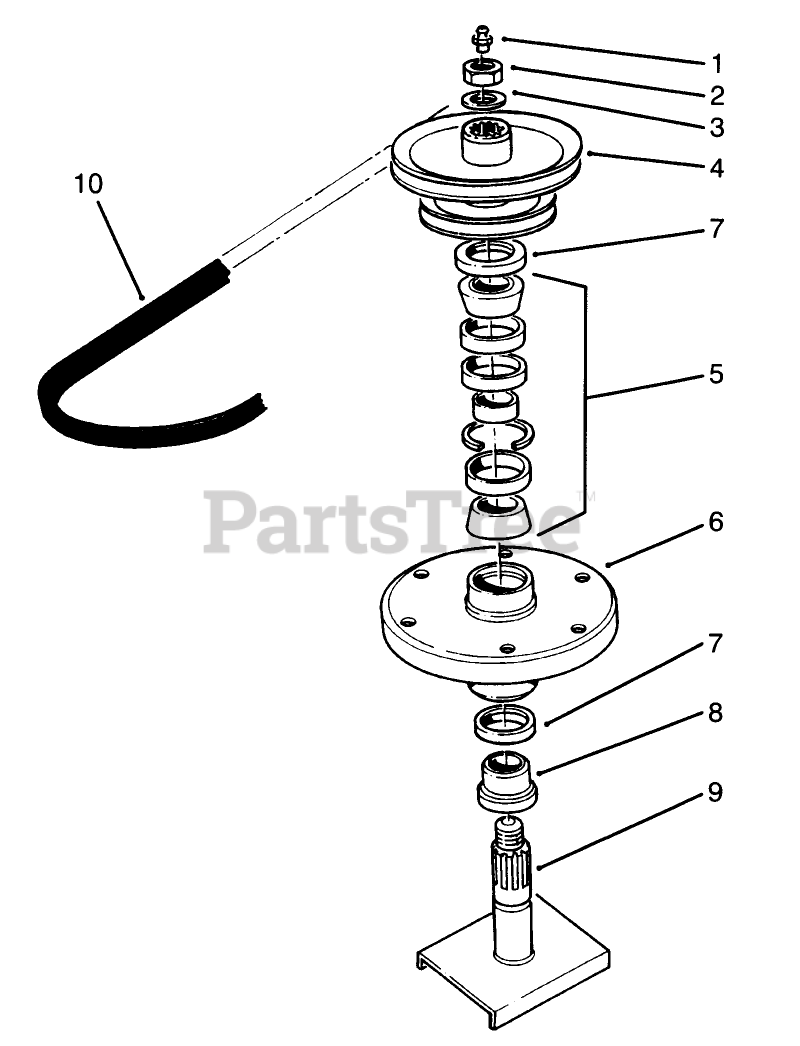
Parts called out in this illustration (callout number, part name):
1	FITTING-GREASE
2	NUT-HEX
3	WASHER
4	PULLEY AND HUB ASM
5	BEARING ASM
6	HOUSING-SPINDLE
7	SEAL-OIL
8	SPACER
9	Shaft-Spindle
10	V-BELT, DRIVE
